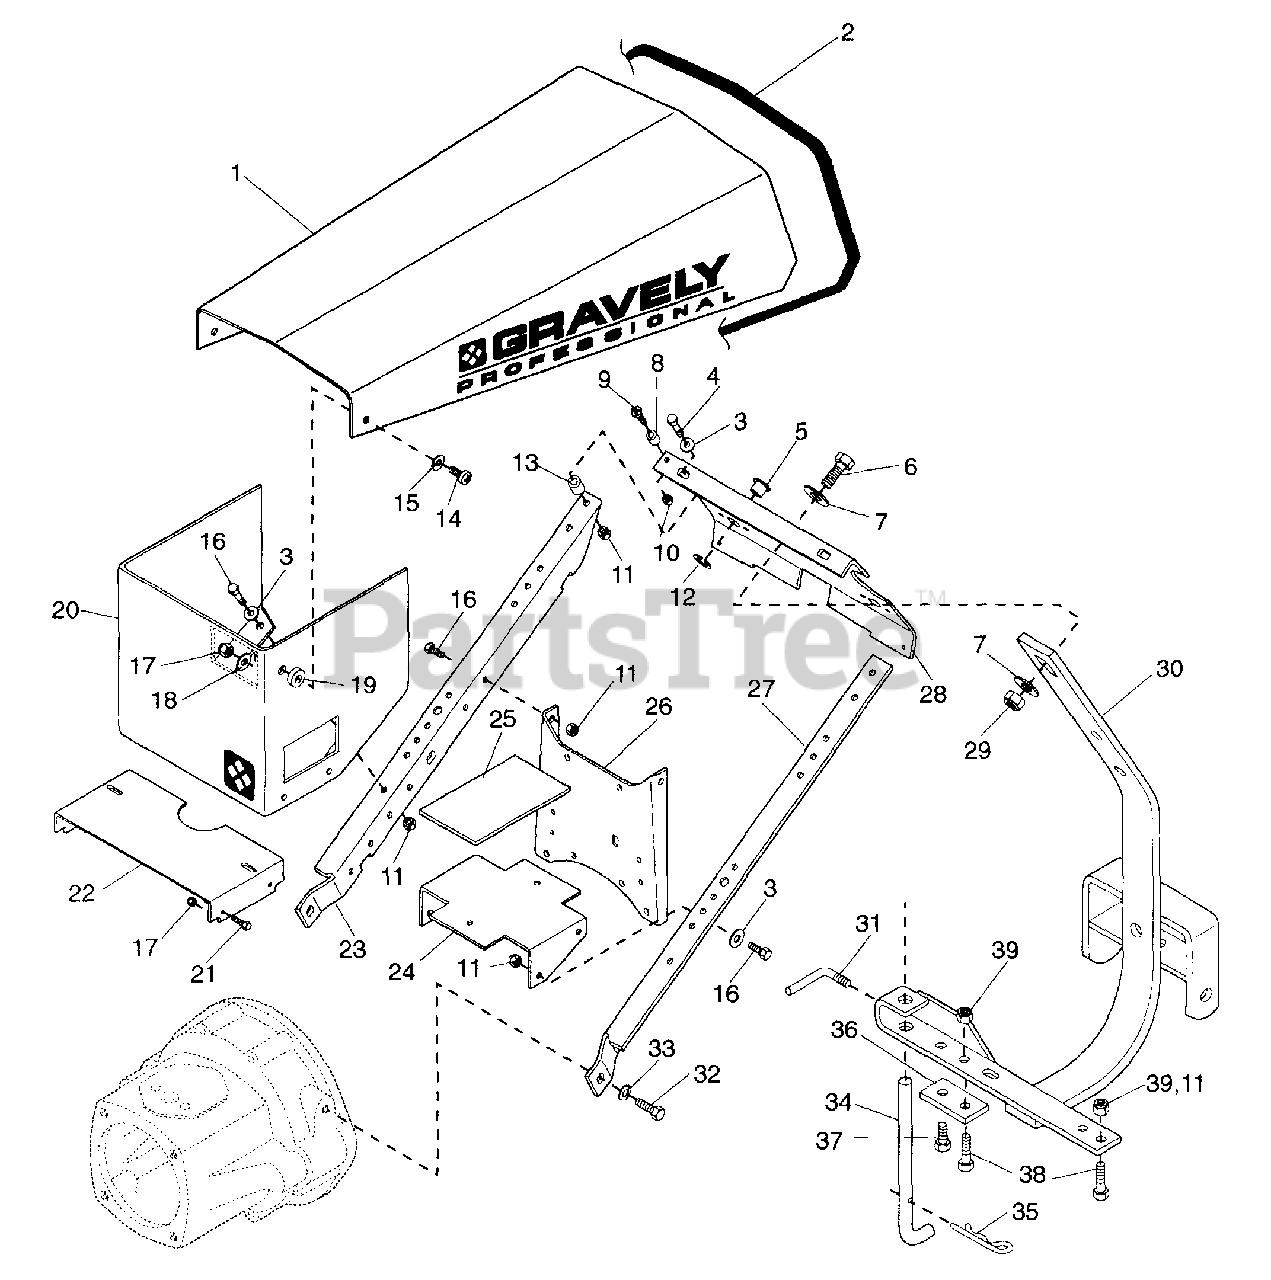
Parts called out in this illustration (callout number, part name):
1	Hood 8 HP
2	Strip, Cowl
3	Washer-Flat-Steel .406 x .812 x .065
4	Bolt-Hex .38-16 x 1.50 Grade 5
5	Bushing-Flange .515 x .750 x .745 x 1.00
6	Bolt-Hex .625-11 x 2.00
7	Washer-Flat-Steel .656 x 1.250 x 1.00
8	Bumper
9	Screw-Machine 6-32 x .625
10	Nut-Locking-Machine 6-32
11	Nut-Locking-Nylon .375-16
12	Ring-Retaining 1.000 x .748
13	Bushing
14	Screw-Machine .50-20 x 1
15	Washer-Flat-Steel .281 x .620 x .065
16	Bolt-Hex .380-16 x .875
17	Nut-Locking-Nylon .250-20
18	Washer-Flat-Steel .313 x .875 x .065
19	Bushing, Flange .280 x .750 x .318
20	Support, Hood
21	Bolt-Hex .25-20 x .63
22	Bracket
23	Support, Handle Bar Right Hand
24	Bracket, Tank Support
25	Pad, Gas Tank
26	Bracket
27	Support Handle Bar Left Hand
28	Plate, Silk Screen Recoil
28	Plate, Silk Screen Elec
28	Plate, Instrument
29	Nut-Locking-Nylon .625-11
30	Weldment, Hitch
31	Handle, Adjusting
32	Bolt-Hex .50-13 x 1 Grade 5
33	Washer-Lock .50 Reg.
34	Stand, Kick
35	Pin-Hair-lnternal .15 x 2.937
36	Bracket
37	Bolt-Hex .31-18 x 1.00 Grade 5
38	Bolt-Hex .38-16 x 2.00 Grade 5
38	Bolt-Hex .31-18 x 2.00 Grade 5
39	Nut-Locking-Nylon .312-18
